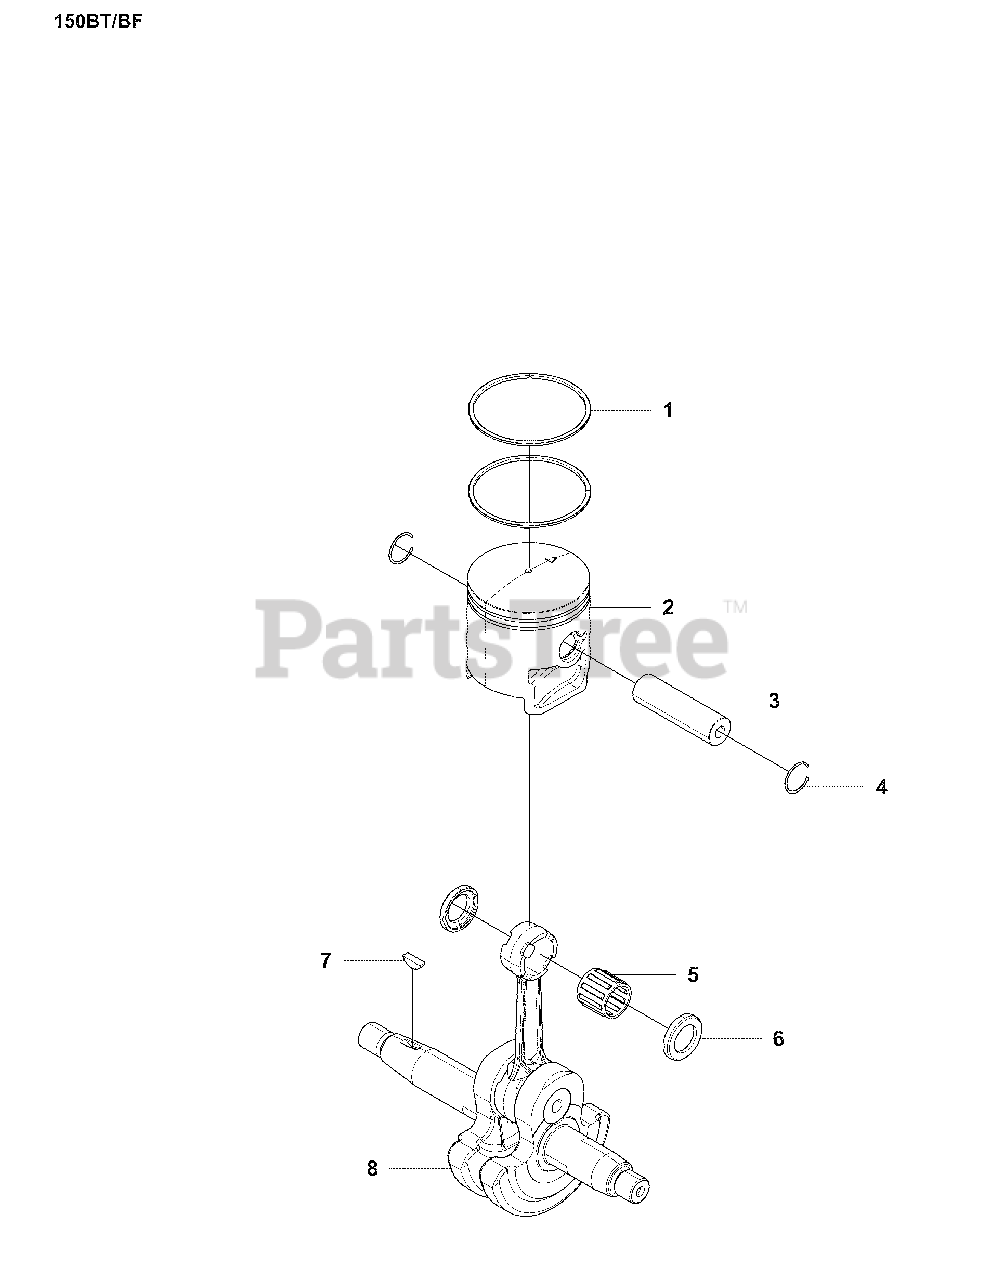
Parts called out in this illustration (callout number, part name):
1	PISTON RING
3	PISTON PIN
7	KEY
8	CRANKSHAFT
